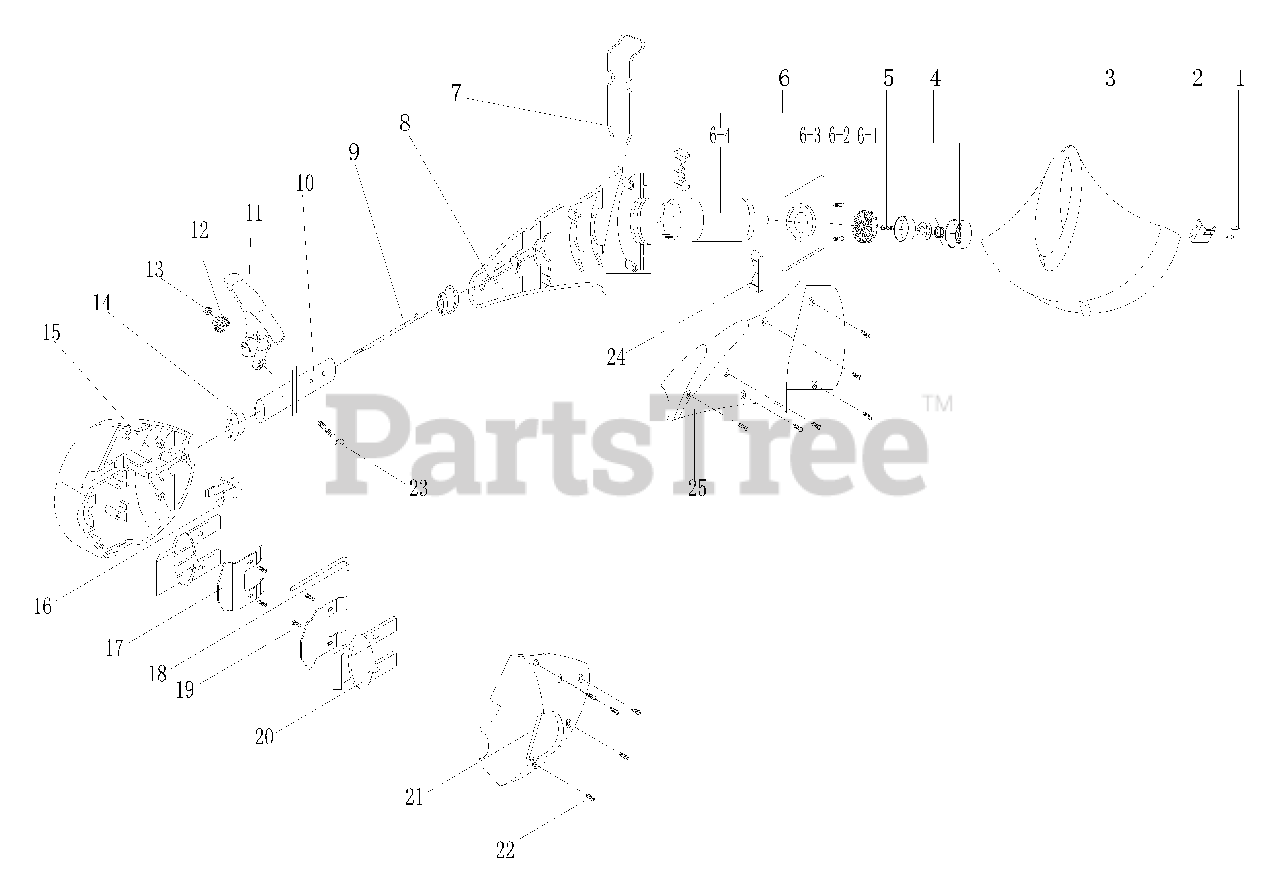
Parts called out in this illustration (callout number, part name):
4	SPOOL ASS'Y
6	MOTOR ASS'Y
8	HOUSING (L)
15	CONNECT (L)
16	TERMINAL ASS'Y
17	SPRING LAMINATION
21	CONNECT (R)
25	HOUSING (R)
